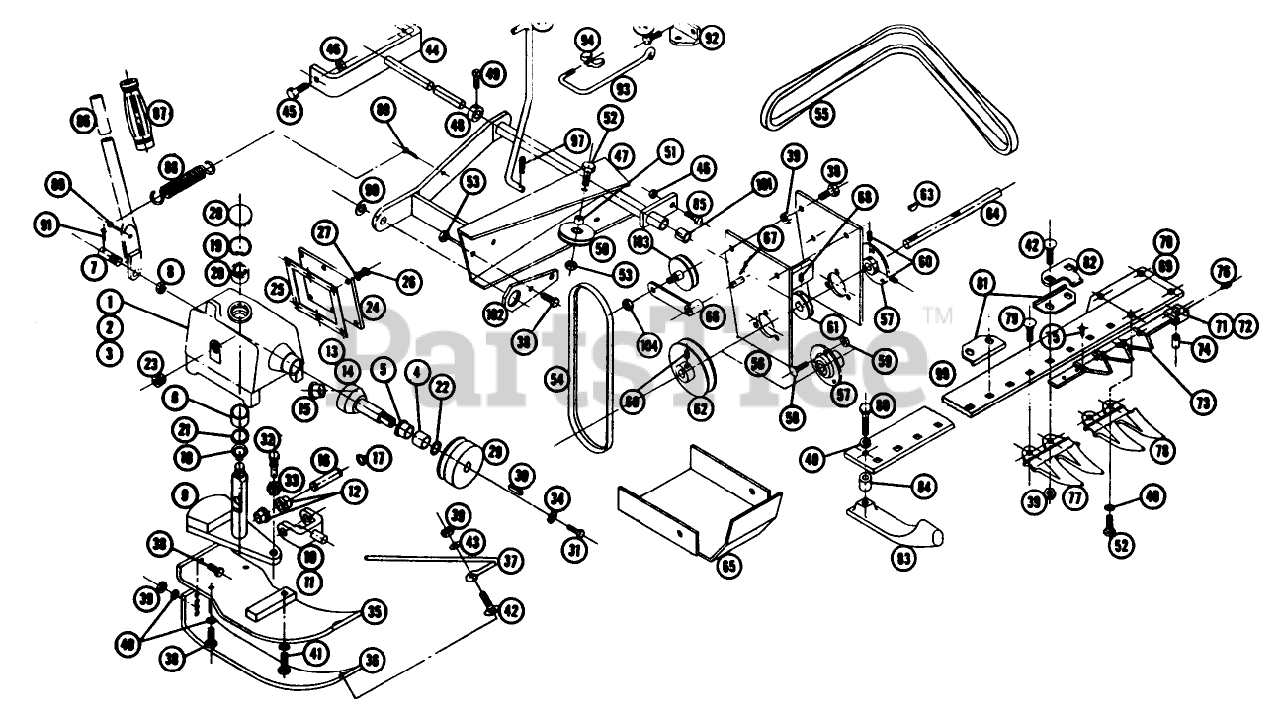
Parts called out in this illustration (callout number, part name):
1	Ass-y Housing Complete-Sickle Drive
2	Ass-y Housings Bearings
3	Housing
6	Bearing-Bronze Sleeve
7	Pin
8	Nut, 3/4-16
9	Ass-y. Shaft-Weldment
10	Ass-y. Yoke
11	Yoke
13	Ass-y. Shaft Bearing
14	Shaft
15	Bearing-Bronze Sleeve
26	Screw-Rd. Hd. #10-24 x 3/8
28	Plug Button
31	Screw - Nylock 3/8-16 x 7/8
32	Pin Sickle Drive
33	Nut-5/8-18
35	Ass y. Shoe-Upper-Weldment
36	Shoe-Lower
38	Bolt 3/8-16 x 1
40	Lockwasher
43	Washer Dia. U.S.
44	Ass-y. Bracket Rod
45	Bolt Hex 1/2-13 x 1
46	Locknut-1/2-13
51	SPACER
52	Bolt 3/8-16 x 1
54	Belt
58	Bolt Hex 5/16-18 x 3/4
59	Nut-Nylok
62	Pulley
63	Key
64	Shaft
65	Shield Pulley
67	Hairpin
68	Set Screw 1/4-20
69	Ass-y. Cutter Bar Complete 42"
70	Ass-y. Bar-Guard
71	Ass-y. Knife Bar Sections
72	Ass-y. Knife Bar-Weldment
73	Section
74	Bushing
75	Rivet
79	Bolt 3/8-16 x 1
80	Bolt, 3/8 16 x 2
81	Wear Plates
85	H.H.C.S. 1/2-13 x 2 1/2
86	Ass-y. Lever Lift
89	Cotter Pin
90	Washer
91	Cotter Pin 3/16 x 1
92	Bracket-Travel Hook
94	3/8 NC Wing Nut
95	Bolt-Hex 1/4-20
100	Decal
102	Link
104	Nut, 1/2-20
